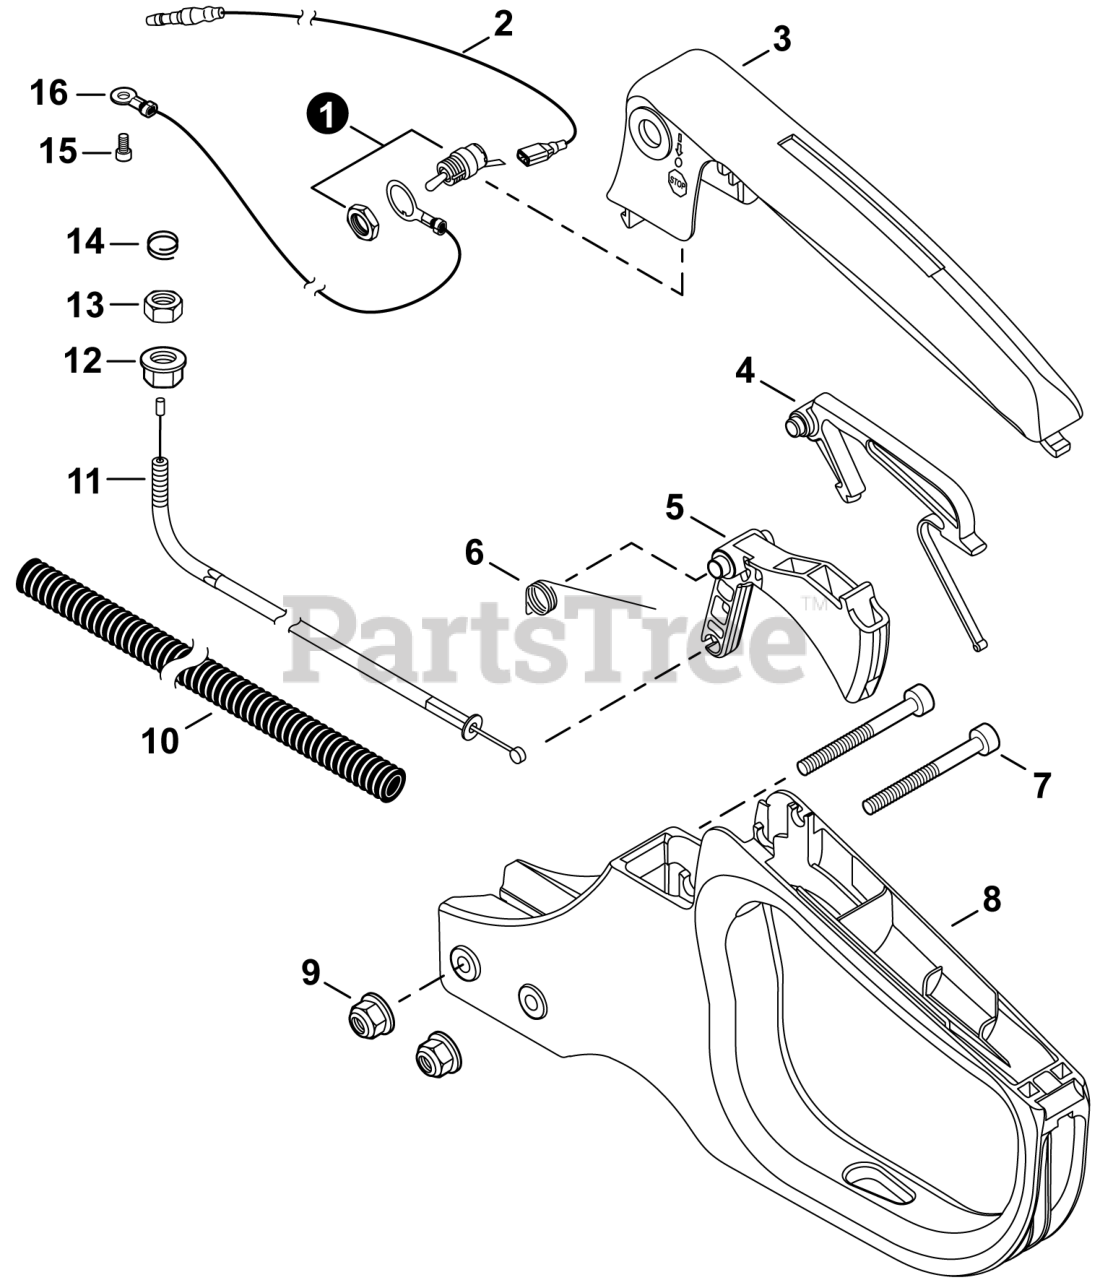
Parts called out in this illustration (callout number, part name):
1	SWITCH, ON-OFF
2	LEAD - IGNITION
3	COVER, HANDLE
4	LOCKOUT, THROTTLE
5	TRIGGER, THROTTLE
6	SPRING, TORSION
7	BOLT, TORX 5×45
8	HANDLE, REAR
9	NUT, FLANGE M5
10	TUBE, FLEXIBLE
11	CABLE, THROTTLE
12	NUT, FLANGE M6
15	BOLT, TORX 4×10
